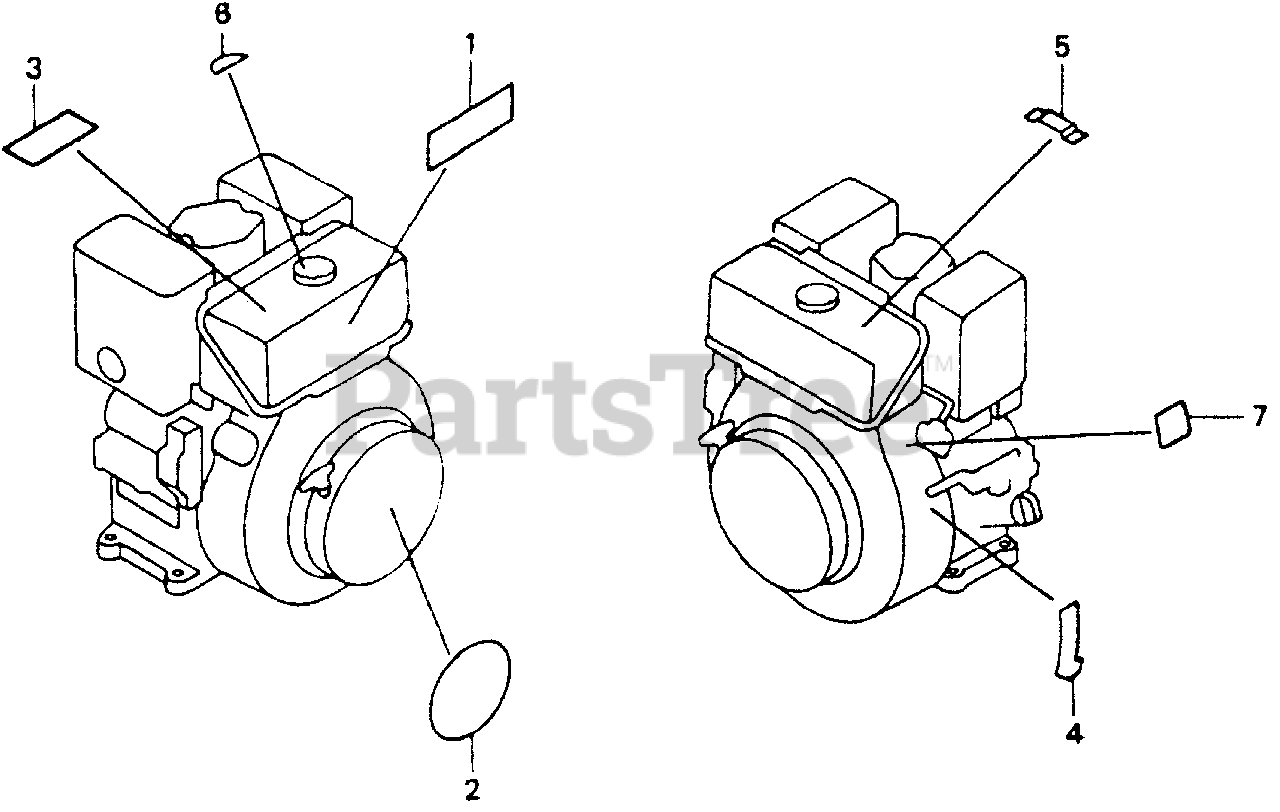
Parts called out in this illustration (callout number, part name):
1	EMBLEM (GD320)
2	PLATE, EMBLEM
3	LABEL, CAUTION (ENGLISH) (ENGLISH)(FRENCH)(GERMAN) (SPANISH)
4	MARK, THROTTLE (E)
5	MARK, FUEL (EXTERNAL)
6	MARK, USE FUEL (E)
7	MARK, OIL CAUTION (E)
